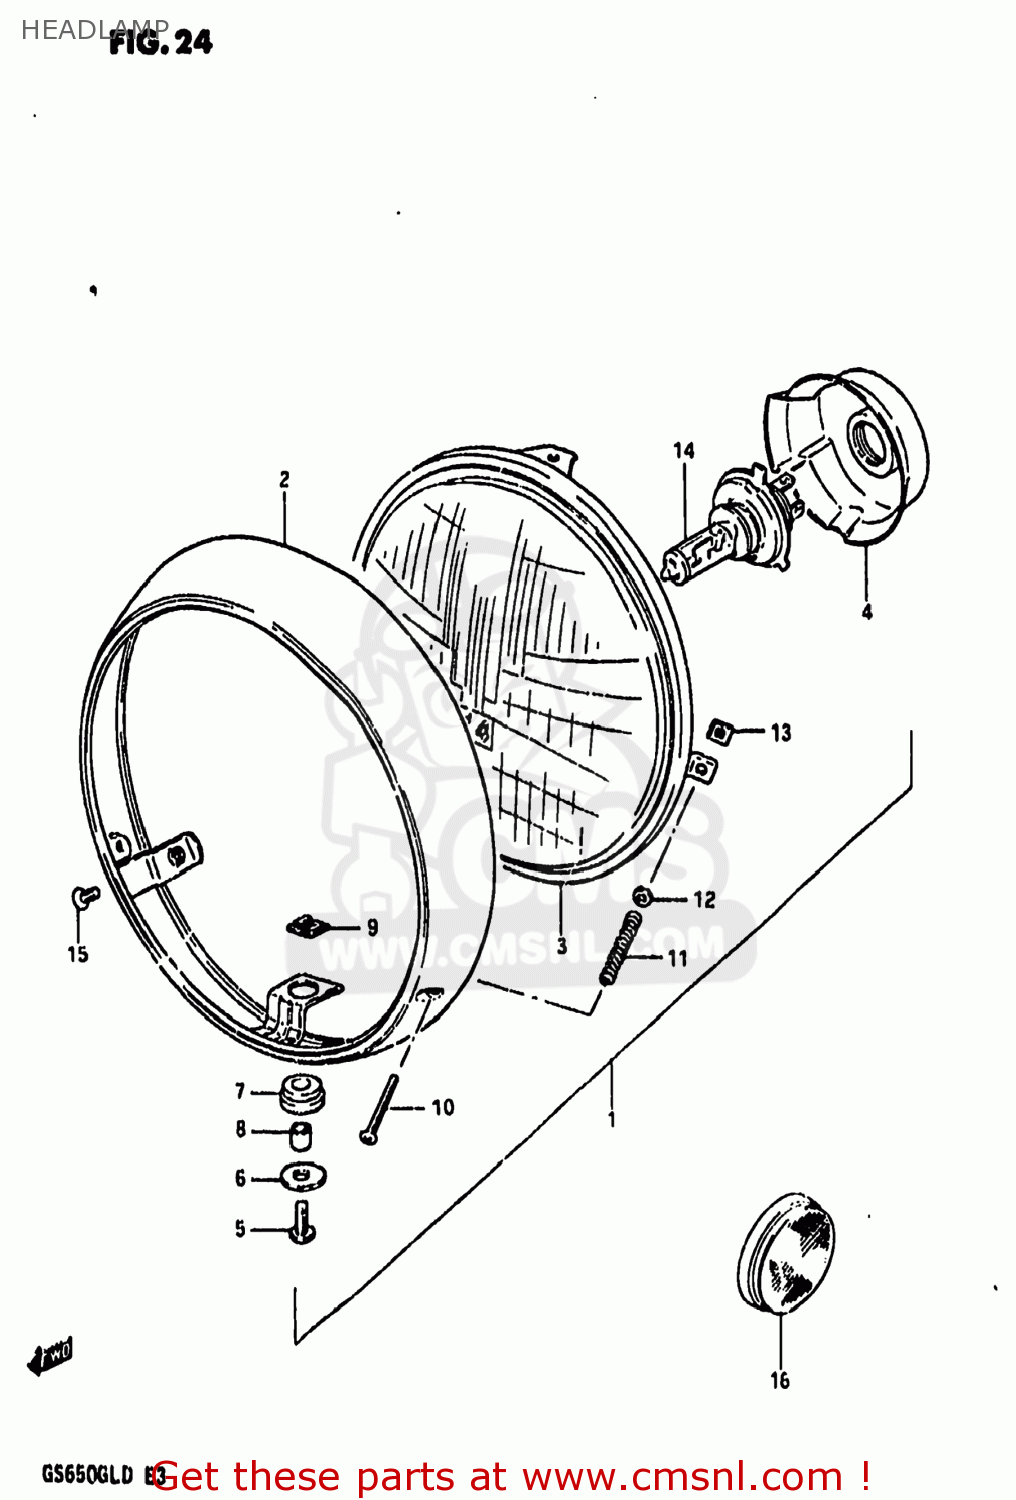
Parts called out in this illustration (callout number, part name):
1	HEADLAMP ASSEMBLY
2	RIM
3	LAMP UNIT
4	COVER,SOCKET
5	SCREW
6	WASHER
7	CUSHION
8	SPACER
9	NUT
10	SCREW
11	SPRING,HEADLAMP ADJUST
12	WASHER
13	NUT,HEADLAMP ADJUSTER
14	BULB(12V60/55W,H4)
15	SCREW(5X12)
16	REFLEX REFLECTOR,RR
